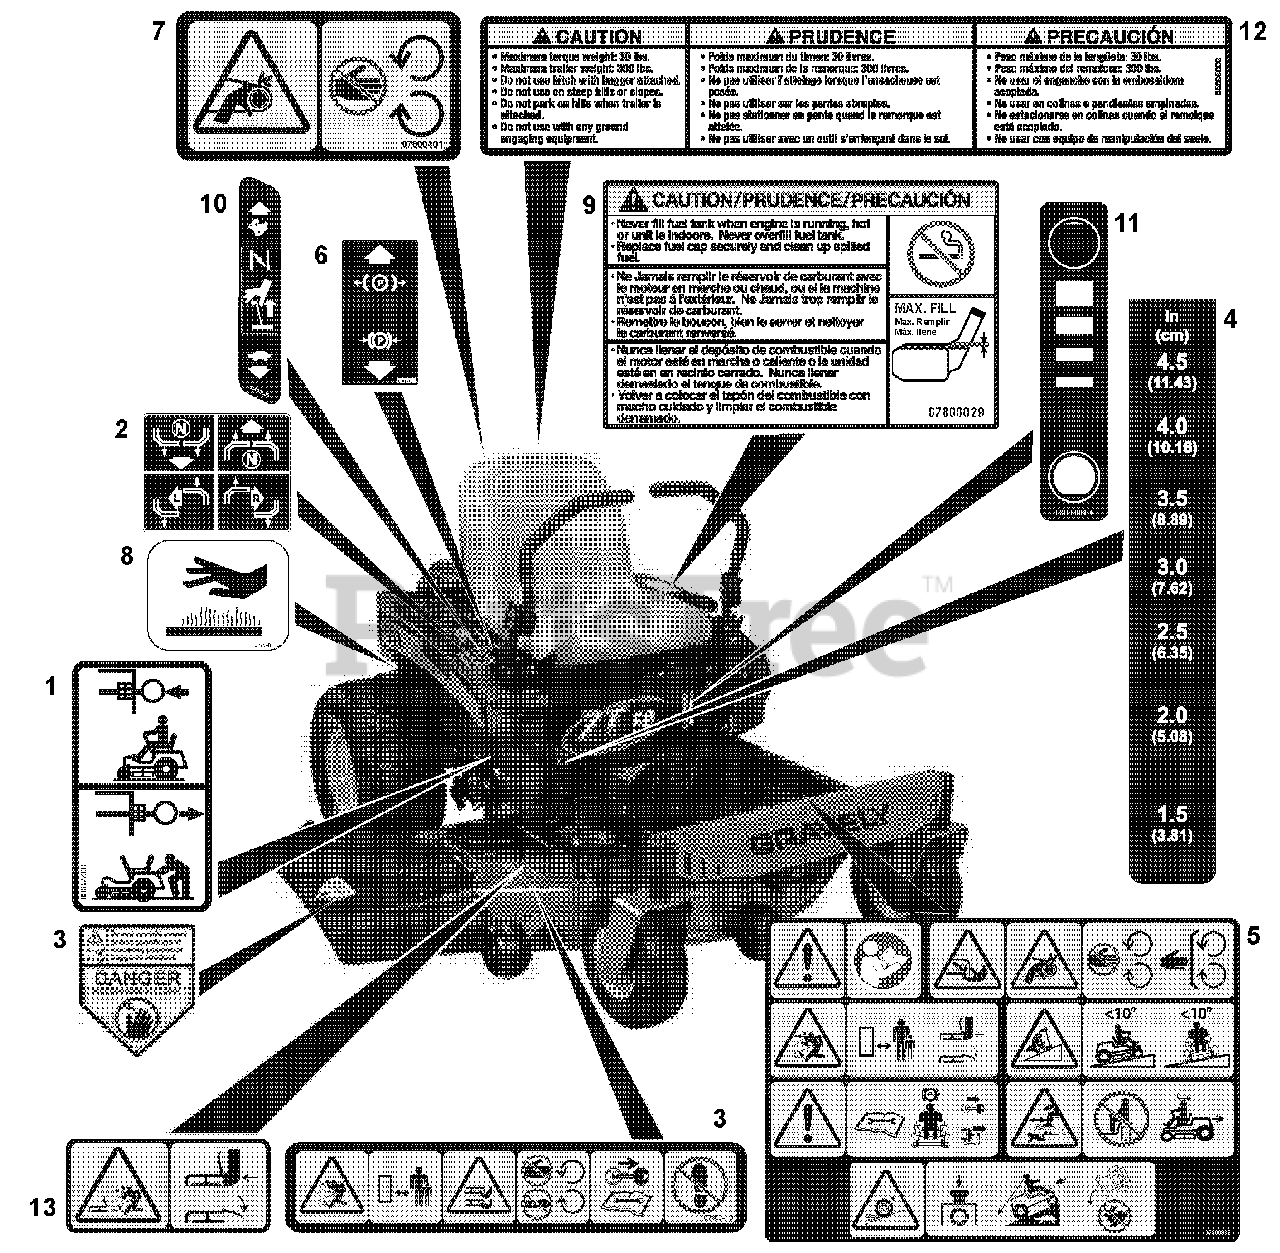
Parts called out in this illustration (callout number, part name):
1	Decal, Transmission Disconnect
2	Decal, Instructional Steering
3	Decal, Safety – Mower Deck
4	Decal, Cut Height
5	Decal, Safety – Main
6	Decal, Parking Brake Lever
7	Decal, Safety – Guarding
8	Decal, Hot Surface
9	Decal, Fuel Warning
10	Decal, Throttle Control (915146, 168)
11	Decal, Fuel Level
12	Decal, Trailer Hitch (915148, 150, 170, 178, 180)
13	Decal, Safety – Deck Guarding
